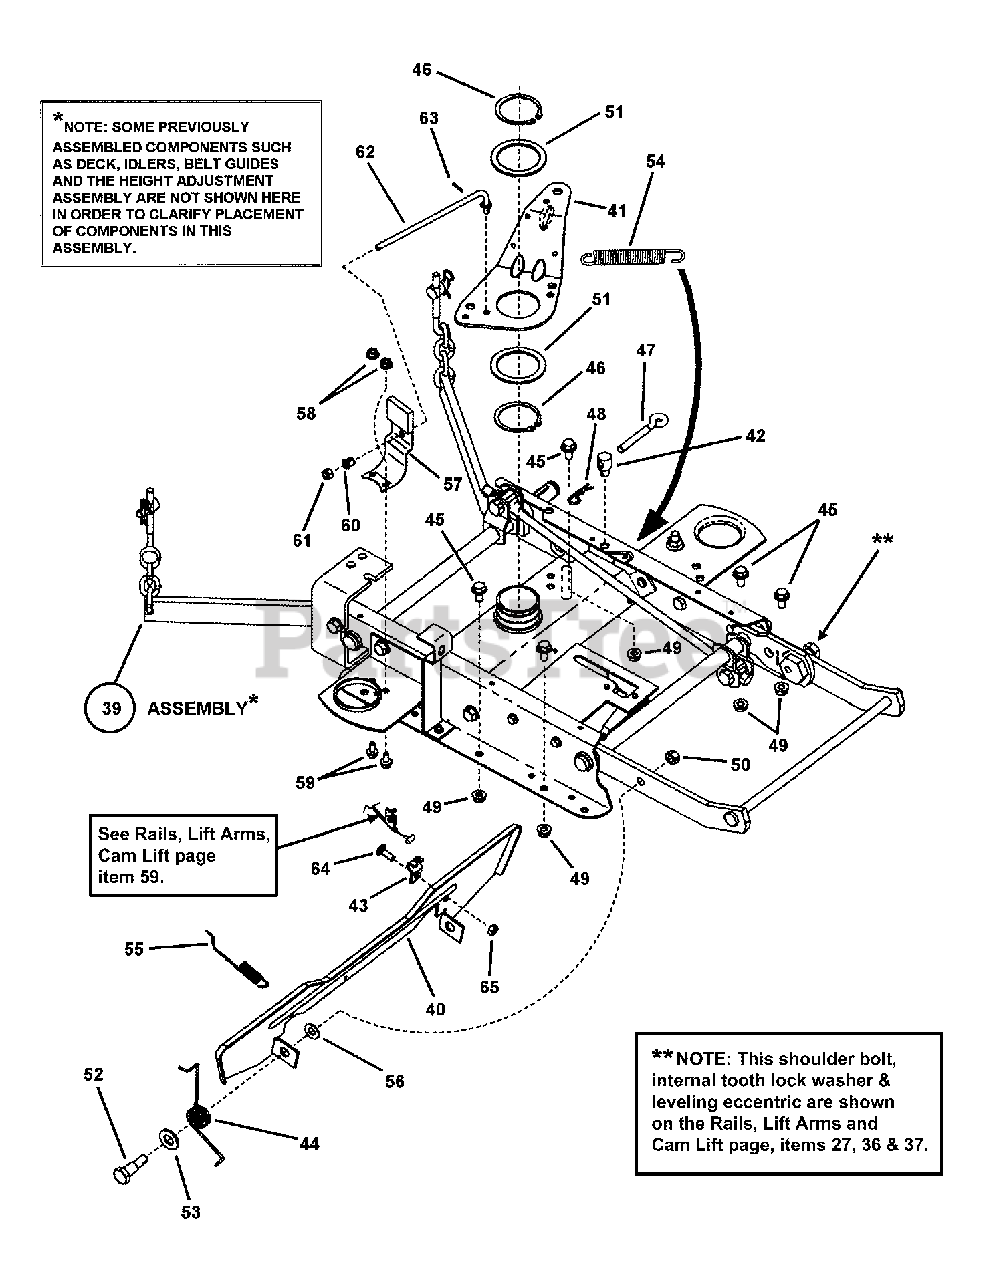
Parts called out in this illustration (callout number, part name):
39	ASSEMBLY, Rail (see Rails, Lift Arms, Cam Lift page for parts breakdown)
40	FOOT PEDAL, Blade Stop Control
41	ARM, Idler
42	SWIVEL, Adjustment (with 5/16-18 internal thread)
43	CABLE CLIP
44	SPRING, Pedal
45	BOLT, 5/16-18 x 5/8" Hex Flange Lock
46	RING, 2" External Retaining
47	EYE-BOLT, 5/16-18 x 3"
48	HAIR PIN, 3/32 x 1-1/2"
49	NUT, 5/16-18 Hex Flange Lock, GR5
50	NUT, 3/8-24 Hex Center Lock
51	WASHER, Nylon
52	SHOULDER BOLT, 3/8-24 x 9/16"
53	WASHER, 1/2" Flat SAE
54	SPRING, Return
55	SPRING, Latch
56	WASHER, 3/8" Flat
57	BRAKE PAD, Spring
58	NUT 1/4-20 Hex Flange Lock
59	BOLT, 1/4-20 x 1/2" Hex Flange Lock
60	BUSHING, .375 Nylon Snap
61	NUT, 1/4-20 Hex Nyloc
62	LINK, Spindle Brake, 1/4-20 thread
63	PIN, 1/16 x 1/2" Cotter
64	BOLT, 1/4-20 x 3/4" Square Neck Carriage, GR5
65	NUT, 1/4-20 Hex, GR5 or B
